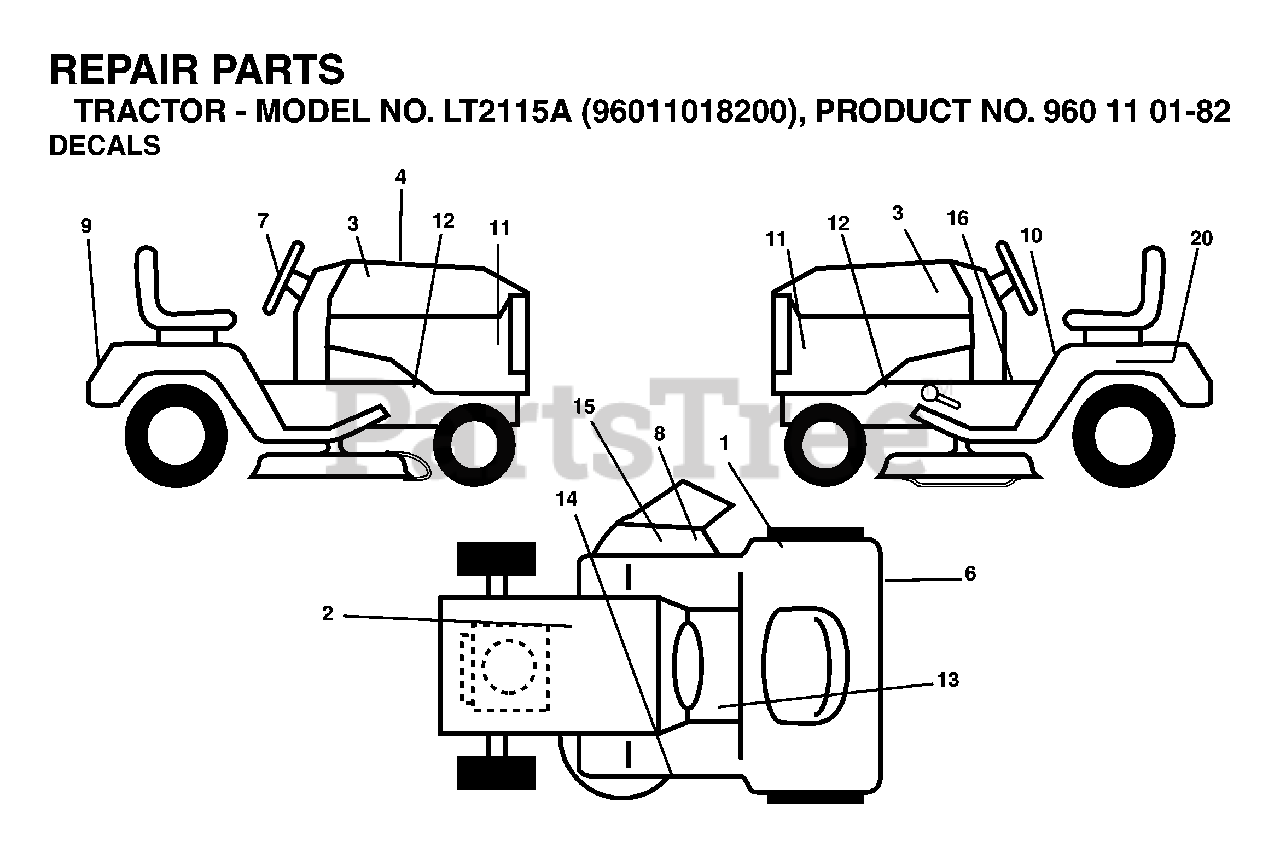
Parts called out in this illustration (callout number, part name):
8	DECAL.INTERNATIONL.CUTFINGER
14	DECAL V BELT SCHEMATIC
15	DECAL, DEFLECT WARNING
16	DECAL PARK BRAKE
20	DECAL BTRY SYMBOLS
